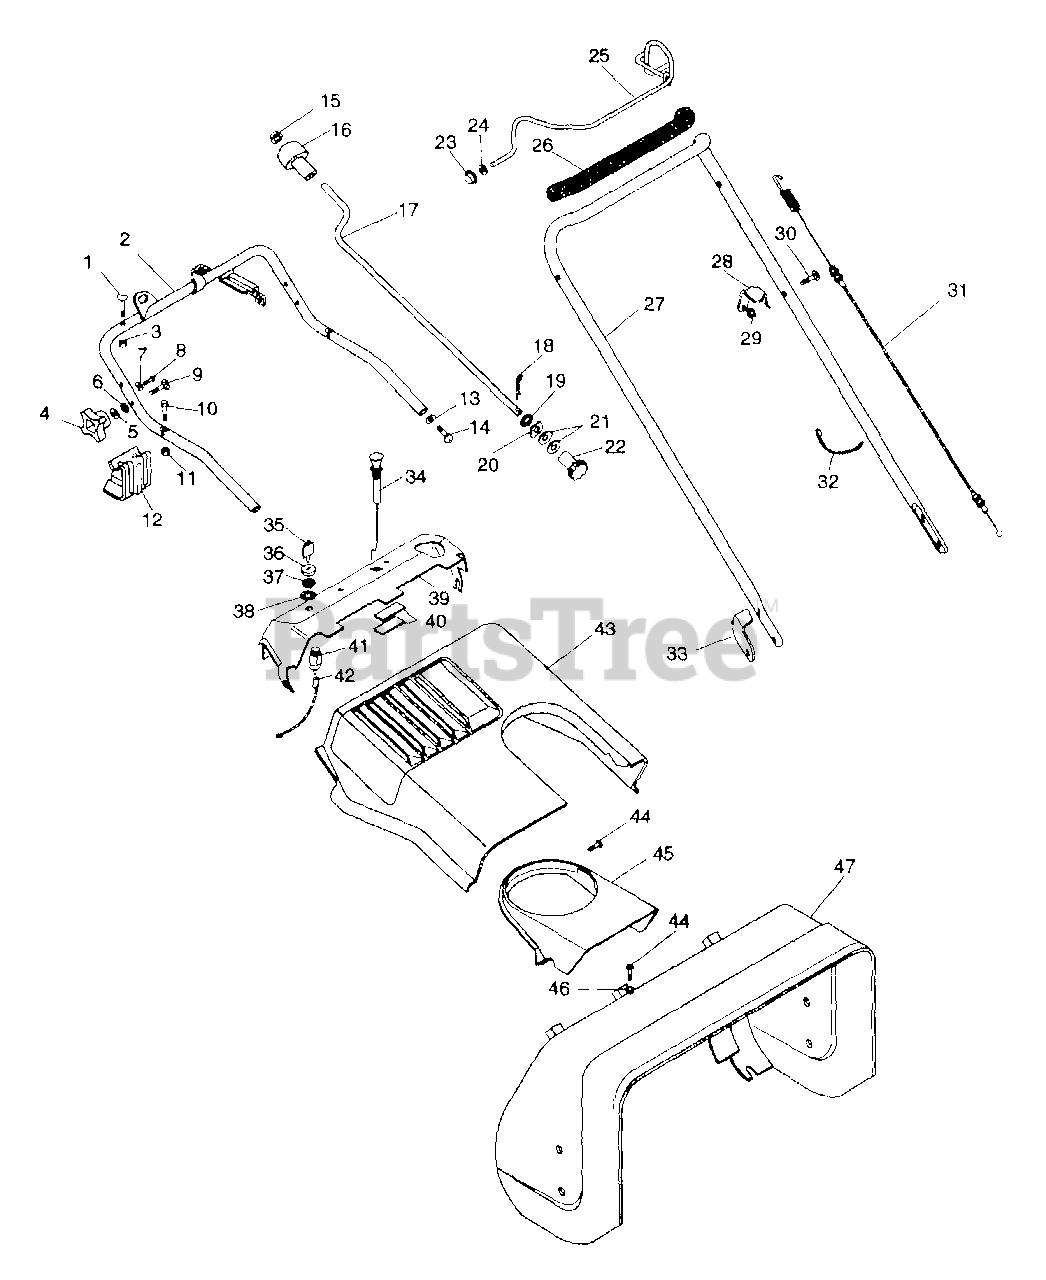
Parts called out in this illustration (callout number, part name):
1	BLT-CRVD-HD .25-20X.25 PL
2	TUBE WELDMENT
3	NUT-LK-FLG .250-20 PL
4	KNOB 5/16-18 UNC
5	WSHR-FL-STL .323X.625X.062 PL
6	WSHR-LK .312X.097 PL HVY
7	WSHR-FL-STL .281X1.250X.048PL
8	SCR-TAP #10-16 X .625 HWH
9	BLT-RDHDSQNK.31-18X2.25 PL
10	SCR-SKH .25-20X1.25 FLTCNTRSK
11	NUT-LK-CTR .250-20 PL
12	SWITCH BRACKET WELDMENT
13	WSHR-FL-STL .328X.875X.062 PL
14	SCR-SKH .31-18X1.25 BTNHD SS
15	CAP, 3/8 ROD YWZC
17	CHUTE CRANK
18	PIN-HAIR INT .08X.38X1.42 YWZC
19	PUSHNUT .625
20	WAVE WASHER .640X.875X.125FH
21	WSHR-FL-STL .630X1.005X.062 PL
23	NUT-PUSH .312 DIA. PAL
24	WSHR-FL-STL .344X.688X.065 PL
25	BAIL
26	HANDLEBAR CUSHION
27	UPPER HANDLEBAR
28	CABLE ANCHOR-LH
29	NUT-LK-FLG .250-20 PL BLK
30	BLT-RDHDSQNK .25-20X1.25 XLGPL
31	CONTROL CABLE
32	CABLE TIE LG 5-1/2
33	STRAP ASSEMBLY
33	LOCK BAR RH
33	LOCK BAR LH
34	CHOKE CONTROL
35	KEY -W/CAP
36	CAP - IGNITION SWITCH
37	NUT-PANEL .625-32 GRECO
38	WSHR-LK-INT .625X.045 PL
39	DASH W/DECAL
40	CATCH ASSEMBLY
41	KEY SWITCH ASSEMBLY
43	ENGINE COVER
44	SCR-TAP 10-24X.50 CRTRH PL AB2
45	INSERT
46	PLASTIC GROMMET
47	AUGER COVER W/DECALS
